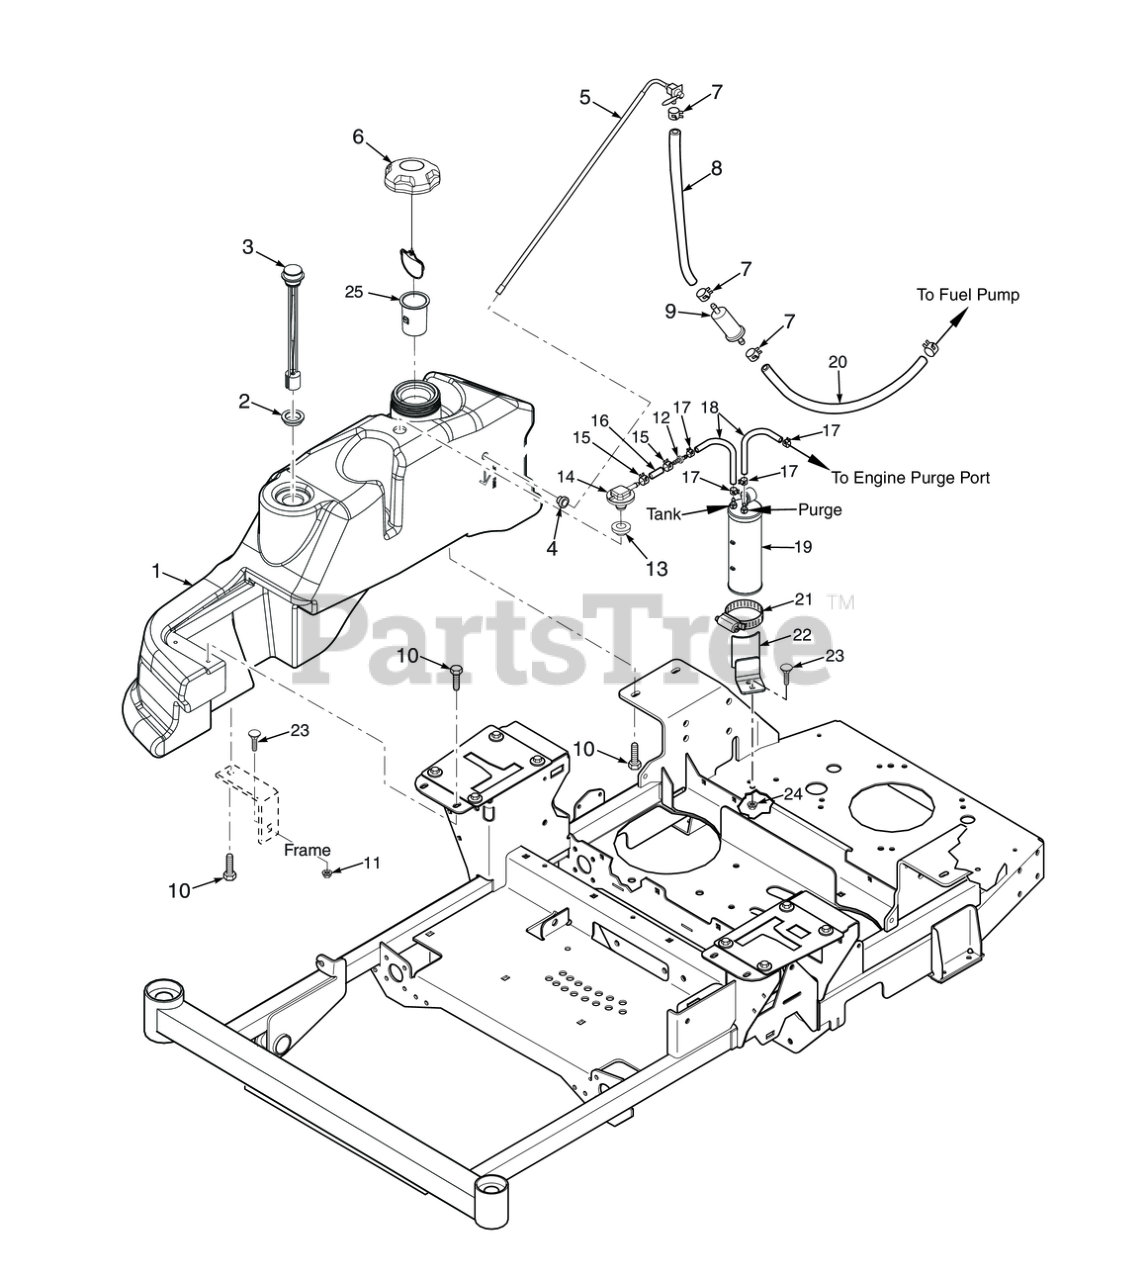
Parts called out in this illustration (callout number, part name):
1	Fuel Tank Assembly - SPZ
2	Grommet, Fuel Gauge
3	Fuel Gauge Assembly
4	Bushing, 0.56" Dia. Viton
5	Fuel Tube Assembly
6	Fuel Cap w/ Tether (E.P.A.)
7	Clamp, Fuel Hose 1/4" Hose I.D.
8	Fuel Hose, 1/4" I.D. Non-Perm (791DFI Fuel Return) - Order by Inch
9	Fuel Filter
10	Capscrew, 5/16-18 x .75 Serrated Flange Hex Head
11	Nut, Flange Head Elastic Stop 5/16-18
12	Mender, 1/4 x 3/16 w/0.02 Hole
13	Grommet, Viton,
14	Remote Vent, No Valve
15	CLAMP, FUEL HOSE(KAWASAKI ONLY)
16	Hose, 1/4" Vapor Recovery (order by inch)
17	Clamp, Vapor Recovery Hose 3/16"
18	Hose, Vapor Recovery 3/16" (order by inch)
19	Carbon Canister - SVR-52V / SVR-61V
20	Fuel Hose
21	Clamp, 3-1/2" Max. Dia.
22	Bracket Weldment, Kohler Models
23	Bolt, 5/16-18 x .75 RHSN Carriage
24	Nut, Serrated Flange 5/16-18 (Right Front Engine Mounting, Briggs and Kohler Only)
25	Tube, Fuel Tank Insert - 4"
